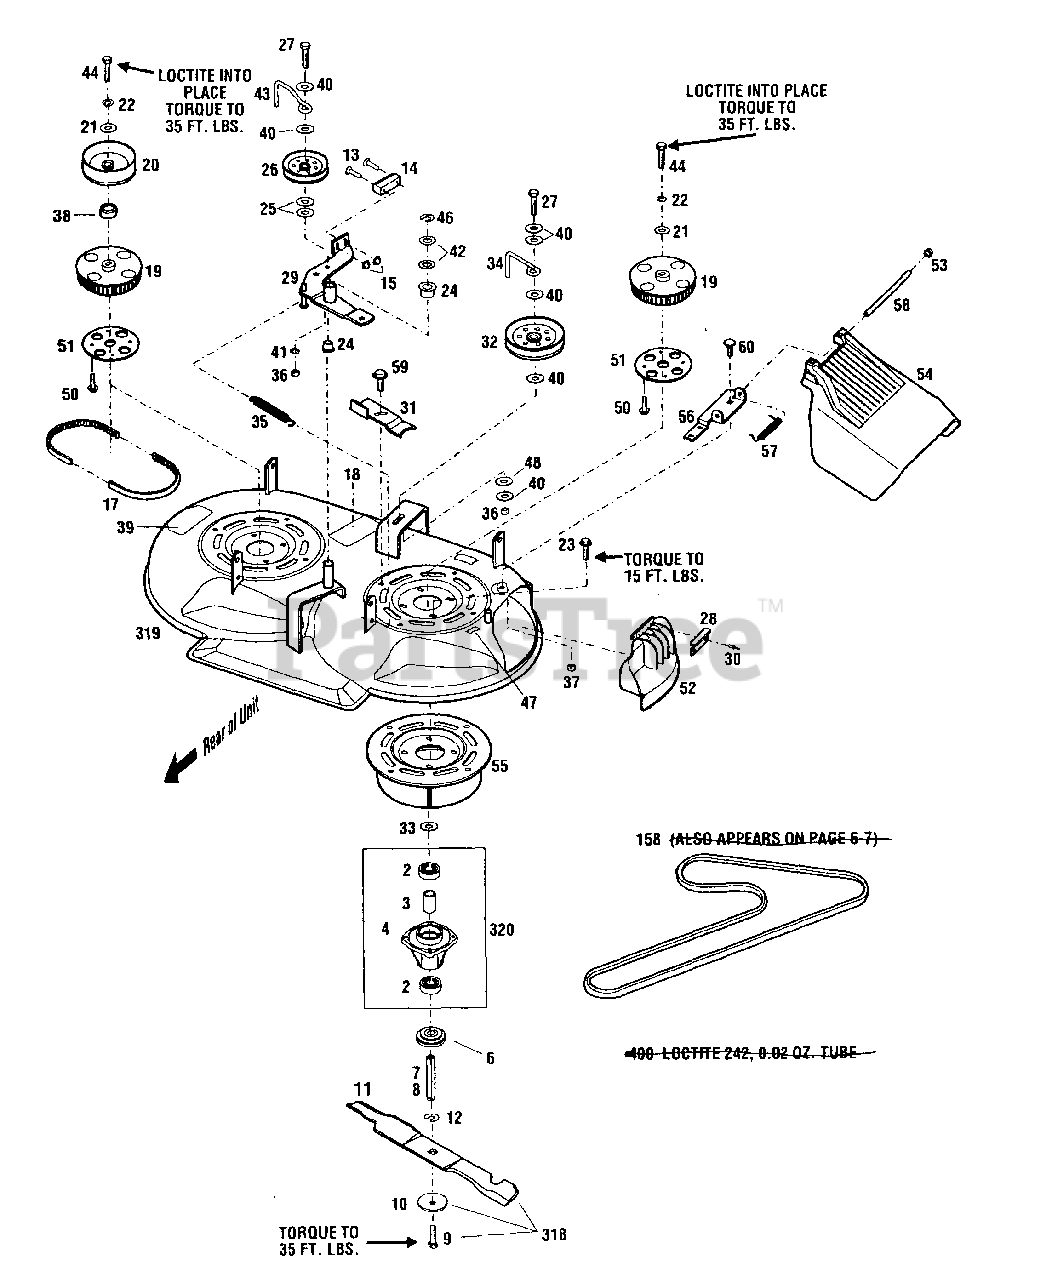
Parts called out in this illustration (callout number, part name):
2	Ball Bearing
4	Mower Spindle
6	Blade Spacer
7	Right Spindle Shaft
8	Left Spindle Shaft (long)
9	Screw, 7/16-14 x 1
10	Belleville Washer
11	Blade, 33" Mulching
12	Retaining Ring
13	Flat Head Screw, #10-24 x 1-1/4
15	Nylon Locknut, #10-24
17	Toothed Drive Belt
18	Caution Decal
19	Cogged Pulley, 56T
20	Drive Pulley
21	Flat Washer, 7/16
22	Lock Washer, 7/16
23	Flange Lock Screw, 5/16-18 x 1
24	Flange Bushing
25	Flat Washer
26	Idler Pulley
27	Hex Head Capscrew, 3/8-16 x 2-1/22
28	Adapter Trim
30	Pop Rivet
31	Belt Tension Adjustment Bracket
32	Idler Pulley
33	Special Thrust Washer
35	Extension Spring
36	Nut, 3/8-16
37	Locknut, 5/16-18
38	Pulley Spacer
39	Danger Decal
40	Flat Washer, 3/8 x 3/4
41	Lock Washer, 3/8
42	Flat Washer
44	Screw, 7/16-14x1-1/4
46	Retaining Ring
47	Warning Decal
48	Pyramid Washer, 3/8
50	Triplask Screw, 1/4-20 x 5/8
51	Sprocket Plate
52	Mulcher Cover, Fold-Up Style
53	Cap
54	Discharge Chute
55	Weldment Doubler
56	Bracket, Chute Hinge
57	Spring, Discharge Chute
58	Pin, Discharge Chute
59	Screw, Thread-Forming
60	Bolt, Carriage, 3/8-18 x 3/4
318	Mulching Blade Kit
319	Mower Deck Assembly
320	Mower Spindle Assembly
